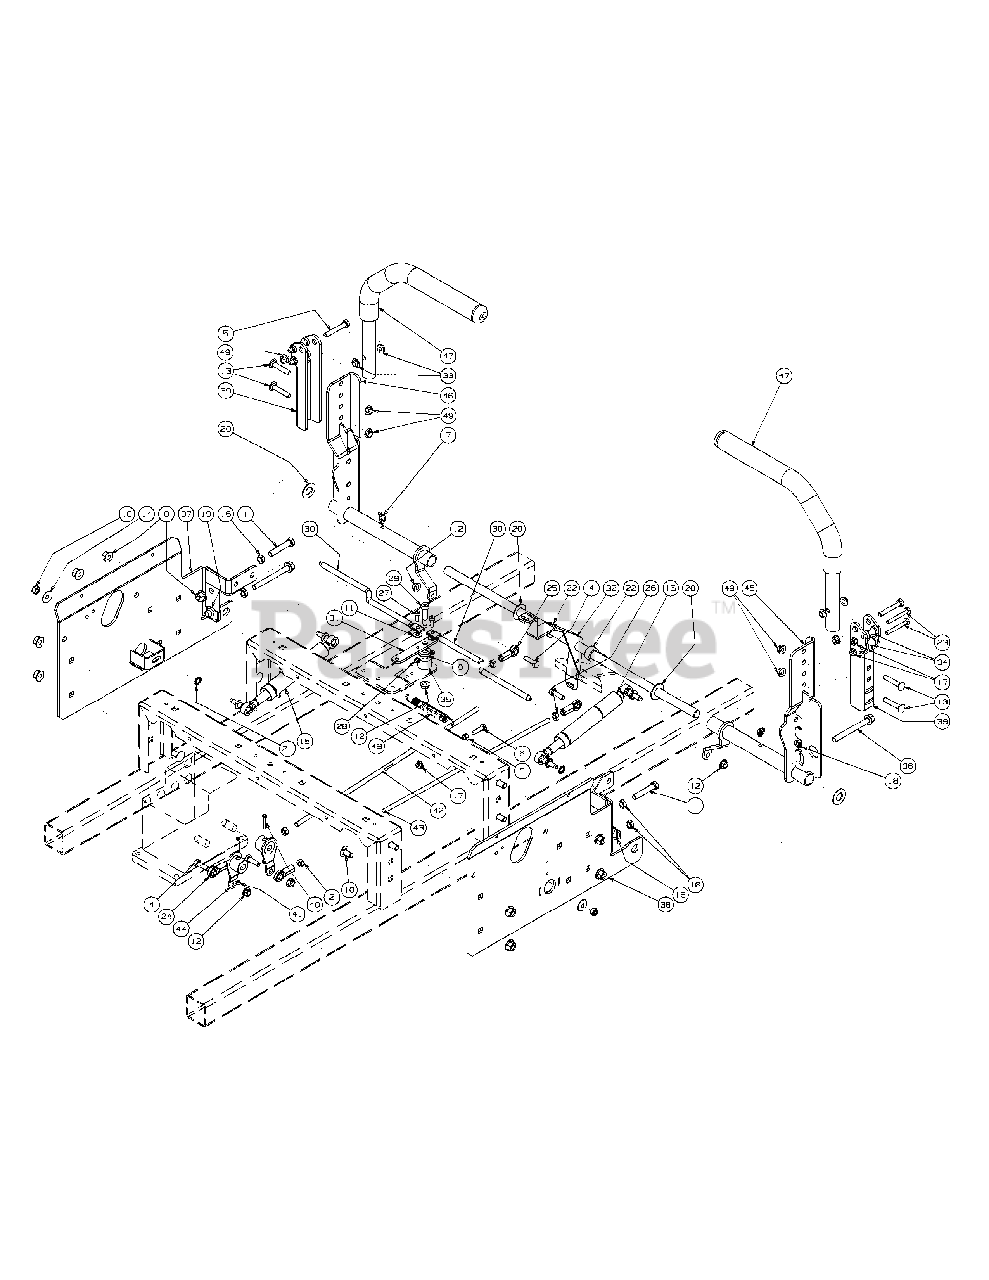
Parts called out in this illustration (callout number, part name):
1	Hex Cap Screw, 3/8-16 x 2.00
2	Hex Nut, 5/16-24
3	Hex Nut, 1/4-20
4	Hex Cap Screw, 5/16-18 x 1.0
5	Hex Cap Screw, 5/16-18 x 2.00
6	HHCS, 1/4-20 x 1.00
7	Grease Fitting, 1/4-28, 45 degree
8	Hex Nut, 3/8-16, Lock Flange
9	Washer, 3/8, SS
10	Carriage Bolt, 3/8-16 x .75
11	Flat Washer, 1.4 x .630 x .0515
12	Nut, Lock, HexFlange, 5/16-18
13	Carriage Bolt, 5/16-18 x 1.75
14	Belle Washer, .325 x .930 x .045
15	Cylinder Return to Neutral
16	Nut, 3/8-16, Jam
17	Hex Flange Lock Nut, 1/4-20
18	Nut, Hex, Center Lock, M8
19	U-Nut, 3/8-16, .75
20	Flat Washer, 5/8 Nylon
21	External Washer, 3/8
22	Shaft Collar
23	Hex Cap Screw, 1/4-20 x 2.00
24	Rod End, 5/16, Right Hand
25	Rod End, 5/16, Left Hand
26	Hex Nut, 5/16-24, Left Hand
27	Shoulder Bolt, 1/4 x 1/4
28	Nut w/ Star Washer, 10-24
29	Screw, Shoulder Control Rod
30	Brake/Control Rod
31	Lapbar Control Arm
32	Lapbar Control Shaft Assembly
33	Bushing, .310 x .172 x .688 x .06
34	Spacer, .251 ID x .38 OD x 1.13 LG
35	Spacer, .405 ID x 1.0 OD x .72
36	Hex Cap Screw, 3/8-16 x 3.50
37	Side Panel, Control, Left
38	Side Panel, Control, Right
39	Lapbar Pivot Bracket
40	Sockethead Capscrew,, M4 x 0.7 x 25mm
41	Nut, M4 x 0.7mm, Nylock
42	Control Rod, 5/16-24, RH/LH x 19.5
43	Control Rod, 5/16-24, RH/LH x 16.5
44	Pump Mount Bracket
45	Lapbar Control Assembly, RH
46	Lapbar Control Assembly, LH
47	Lapbar Assembly includes:
48	Extension Spring, .53 OD x 4.75
49	Nut, Lock, HexFlange, 5/16-18
